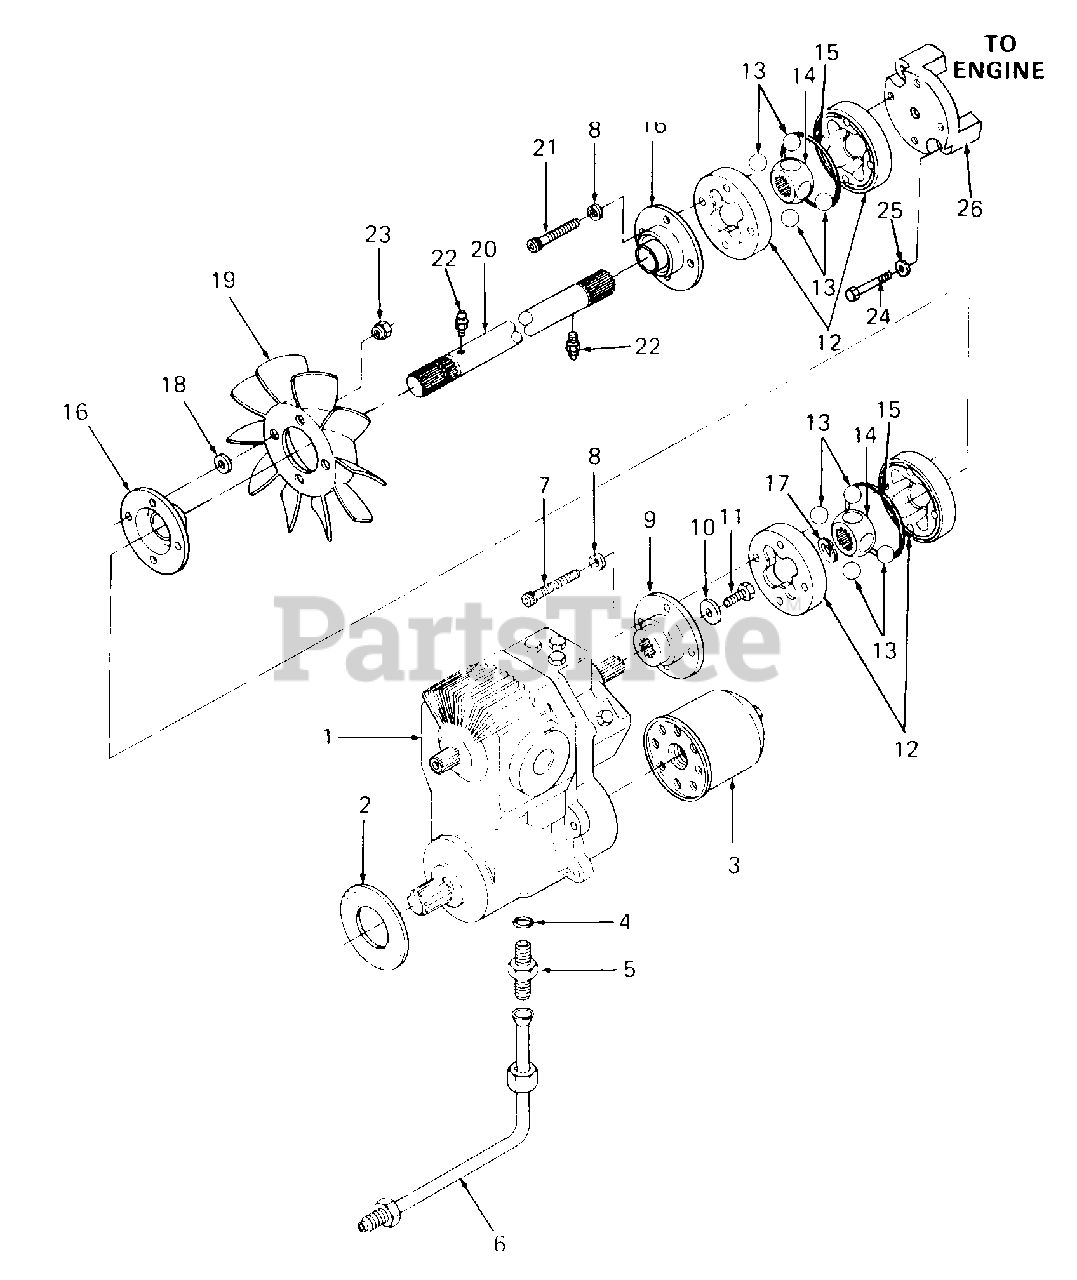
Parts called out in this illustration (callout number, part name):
1	Pump, Hydrostatic
2	Gasket, Front
3	Filter, Oil
4	O-Ring, 5/8 OD Tube
5	Connector, 37 Degree
6	Tube Assy
7	Screw, Socket Hd Cap, 1/4-20 X 2.0 Lg
8	Washer, Lock, 1/4
9	Adapter, Pump
10	Washer, Bell, .265 X .75 X .062 Thk
11	Bolt, Hex Patch, 1/4-20 X 1.0 Lg GR5
12	Coupling, Drive w/O-Ring Groove
13	Ball, Steel, 5/8 Dia Chrome
14	Hub, Drive
15	O-Ring, 2.489 X .070
16	Boot, Coupling
17	Ring, Snap
18	Washer, Flat, .25 X .62 X .052 Thk
19	Fan, 10 Blade Hydro
20	Shaft, Drive, 20.38 Lg
21	Screw, Socket Hd Cap, 1/4-20 X 1.75 Lg
22	Fitting, Grease
23	Nut, Fan, 1/4-20
24	Bolt, Hex Patch, M8-1.25 X 50 MM
25	Washer, Flat, .312 X .750 X .119 Thk ..
26	Adapter, Drive Shaft
